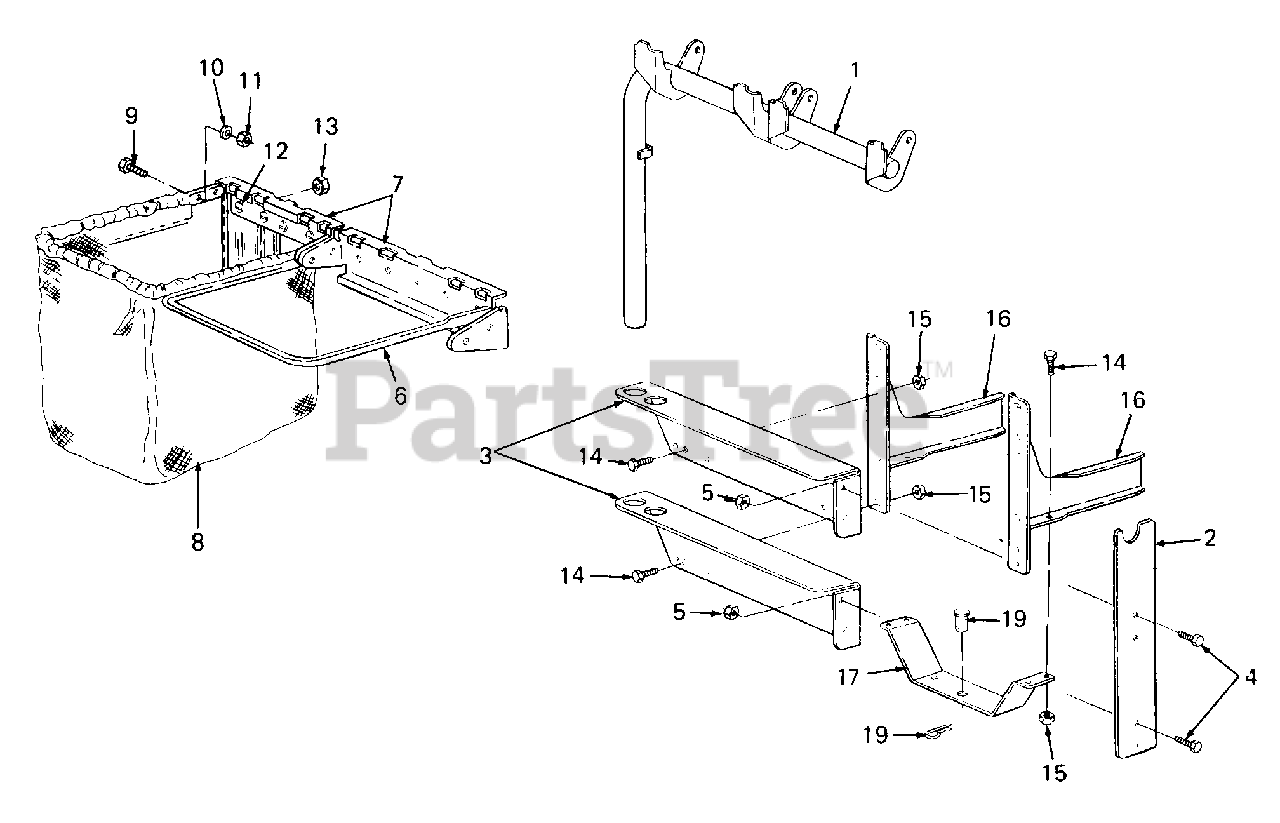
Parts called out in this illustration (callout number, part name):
1	Tube Assy, Support
4	Screw, Hex Cap, 5/16-18 x .75 Lg
5	Nut, Hex Flange Top Lock 5/16-18 GR5
8	Bag, Grass Catcher
9	Screw, Hex, 1/4-28 x .75 Lg
10	Washer, Lock, 1/4
11	Nut, Hex, 1/4-28
12	Screw, Truss Mach, #1 0-24 x .38 Lg
13	Nut, Hex Sems, #10-24
14	Screw, Hex, 1/4-20 x .62 Lg GR5
15	Nut, Hex, 1/4-20 GR5
19	Pin, Internal Cotter - Quick Attach
